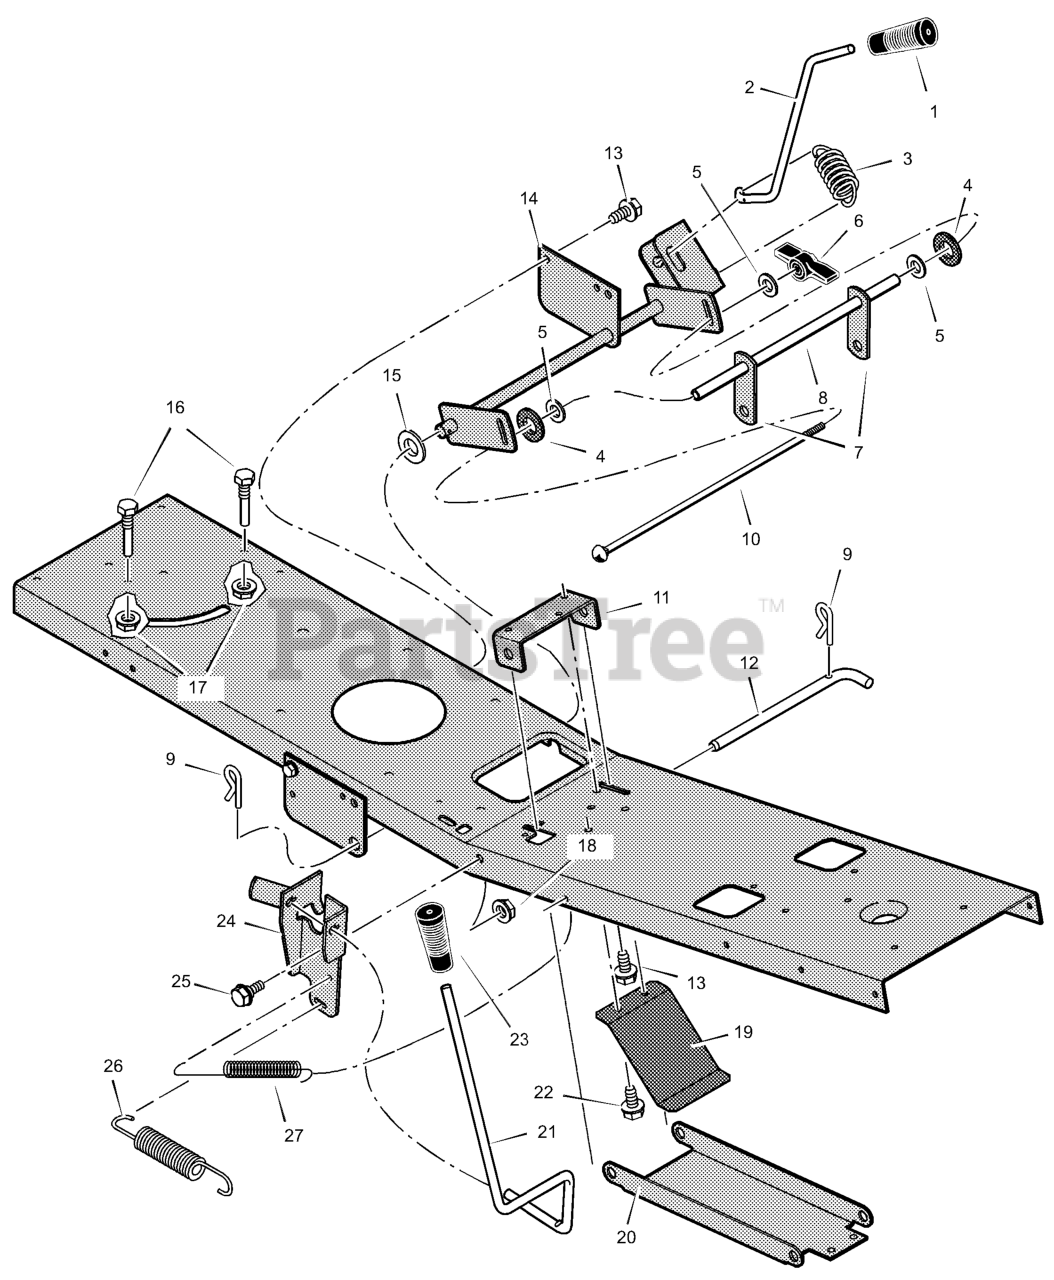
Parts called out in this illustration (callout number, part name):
1	Grip, Lift Lever
2	Lever, Lift
3	Spring, Extension
4	Pad, Friction
6	Wingnut
7	Link, Lift
8	Tube, Spacer
9	Pin, Hair
10	Bolt, Carriage
11	Bracket, Front Hanger Pivot
12	Pin, Front Hanger
14	Arm Assembly, Lifter
15	Washer
16	Screw, Guide
17	Nut, Flange
18	Nut, Flange
19	Spring, Leaf
20	Hanger, Front
21	Lever, PTO
23	Grip, PTO
24	Bracket, PTO
25	Bolt, Shoulder
26	Spring, Extension
27	Spring, Extension
